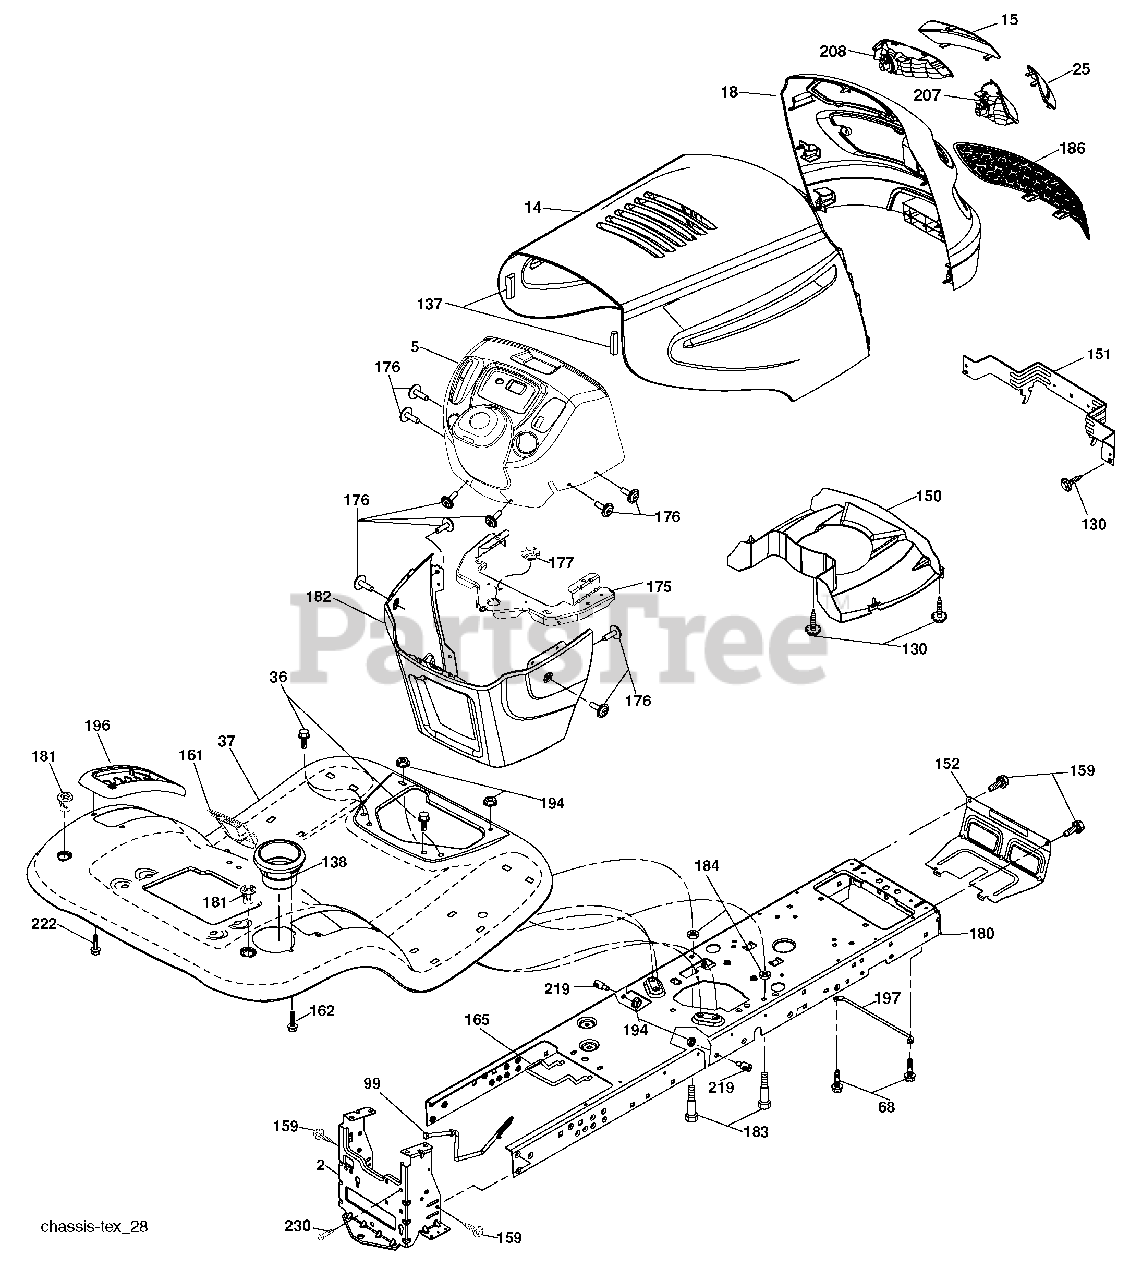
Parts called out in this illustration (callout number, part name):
2	Drawbar
5	Dash
14	Hood
15	Lens Grille LH
18	Grille
25	Lens Grille RH
36	Screw 5/16-18 x 3/4
37	Fender
68	Screw THDROL 5/16-18 x 1/2
99	Rod Bypass Asm
130	Screw 10 x 3/4 Single Lead-Hex
137	Bumper Hood
138	Cupholder
150	Duct Heat Hood
151	Bracket Pivot
152	Shield Browning/Debris
159	Screw Hexwsh Thdrol 3/8-16 x 3/4
162	Screw Hex Wsh Hi-Lo 1/4 x 1/2 UNC
175	Crossmember
176	Screw 10-24 x 5/8 Wshd Qdrx
177	Bushing Steering
181	Bushing Mtg. Fender Crgo.
182	Dash Lower
183	Bolt Fin Hex 5/16-18 x 1-1/4
184	Spacer Fender
189	Screw 5/16-18 x 3/4
194	Nut Lock Hex Flange 5/16-18
196	Console Asm. Deck Lift
197	Rod Pivot Chassis
207	Bezel RH
208	Bezel LH
219	Stud Fastener
222	Screw thd Roll 1/4-20 x 5/8
229	Screw 3/8-16 x 1
230	Bolt Shoulder 5/16-18
230	Plug Cruise/Hook/Phone
